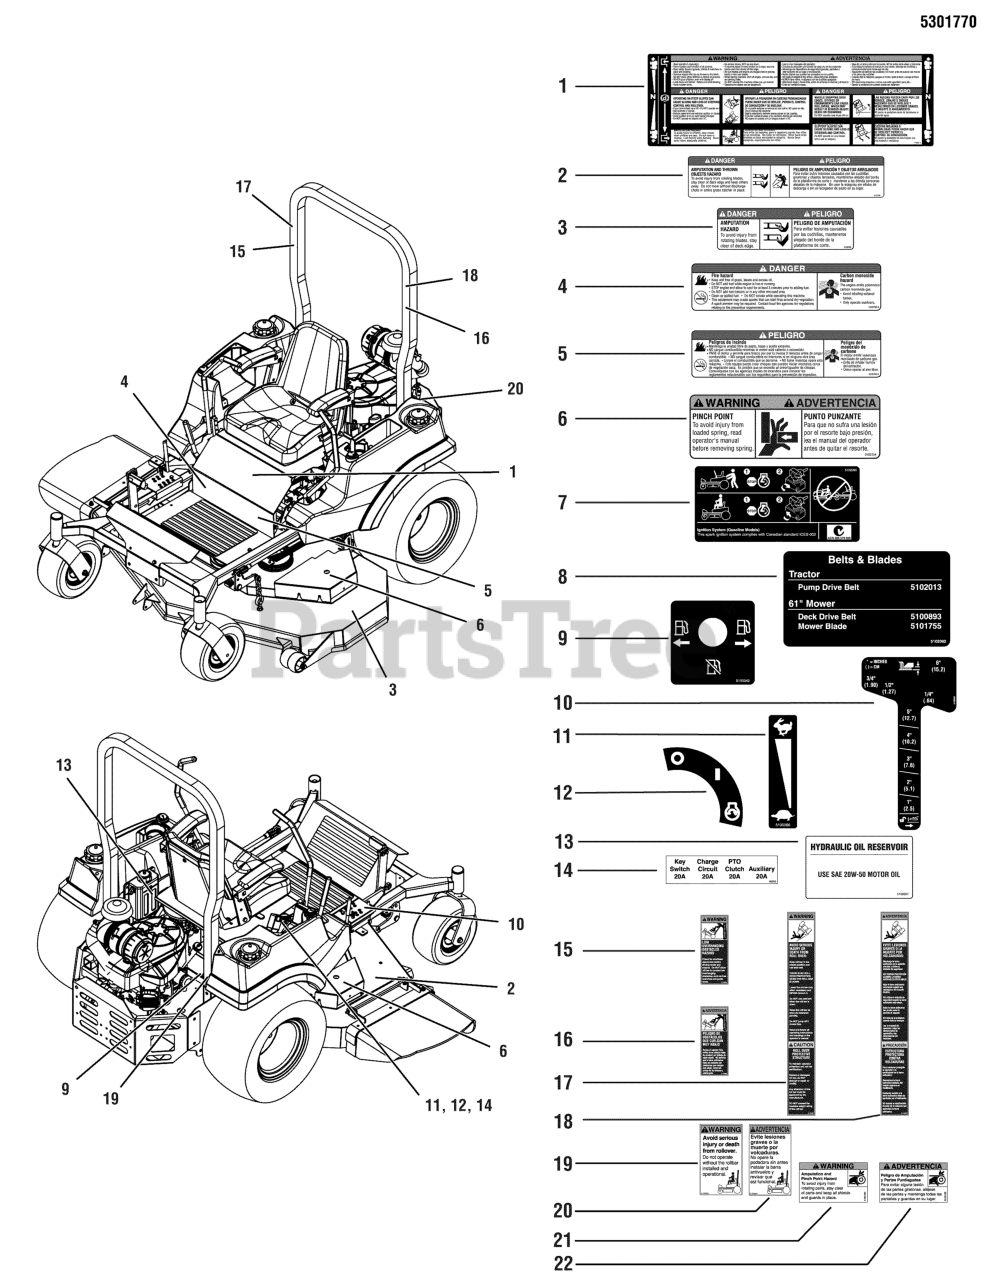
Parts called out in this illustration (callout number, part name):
1	DECAL, MAIN SAFETY
2	DECAL, DANGER, MOWER DISCHARGE,9.75X2.13
3	DECAL, DANGER, MOWER
4	DECAL, DANGER, FIRE
5	DECAL, DANGER, FIRE (SP)
6	DECAL, WARNING, PINCH POINT
7	DECAL, TRANSAXLE RELEASE, S200XT
8	DECAL, BELT & BLADE, S200XT
9	DECAL, FUEL VALVE
10	DECAL, DECK HEIGHT, 1-1/2 TO 6, S200XT
11	DECAL, THROTTLE CONTROL
12	DECAL, IGNITION SWITCH
13	DECAL, HYDRAULIC OIL, SAE 20W50
14	DECAL, FUSE LOCATION
15	DECAL, WARNING, ROLL BAR (SV)
19	DECAL, WARNING, ROLL BAR
20	DECAL, WARNING, ROLL BAR, SP
21	DECAL, WARNING, HAND IN BELT, ENG ONLY
22	DECAL, WARNING, HAND IN BELT, SPA ONLY
